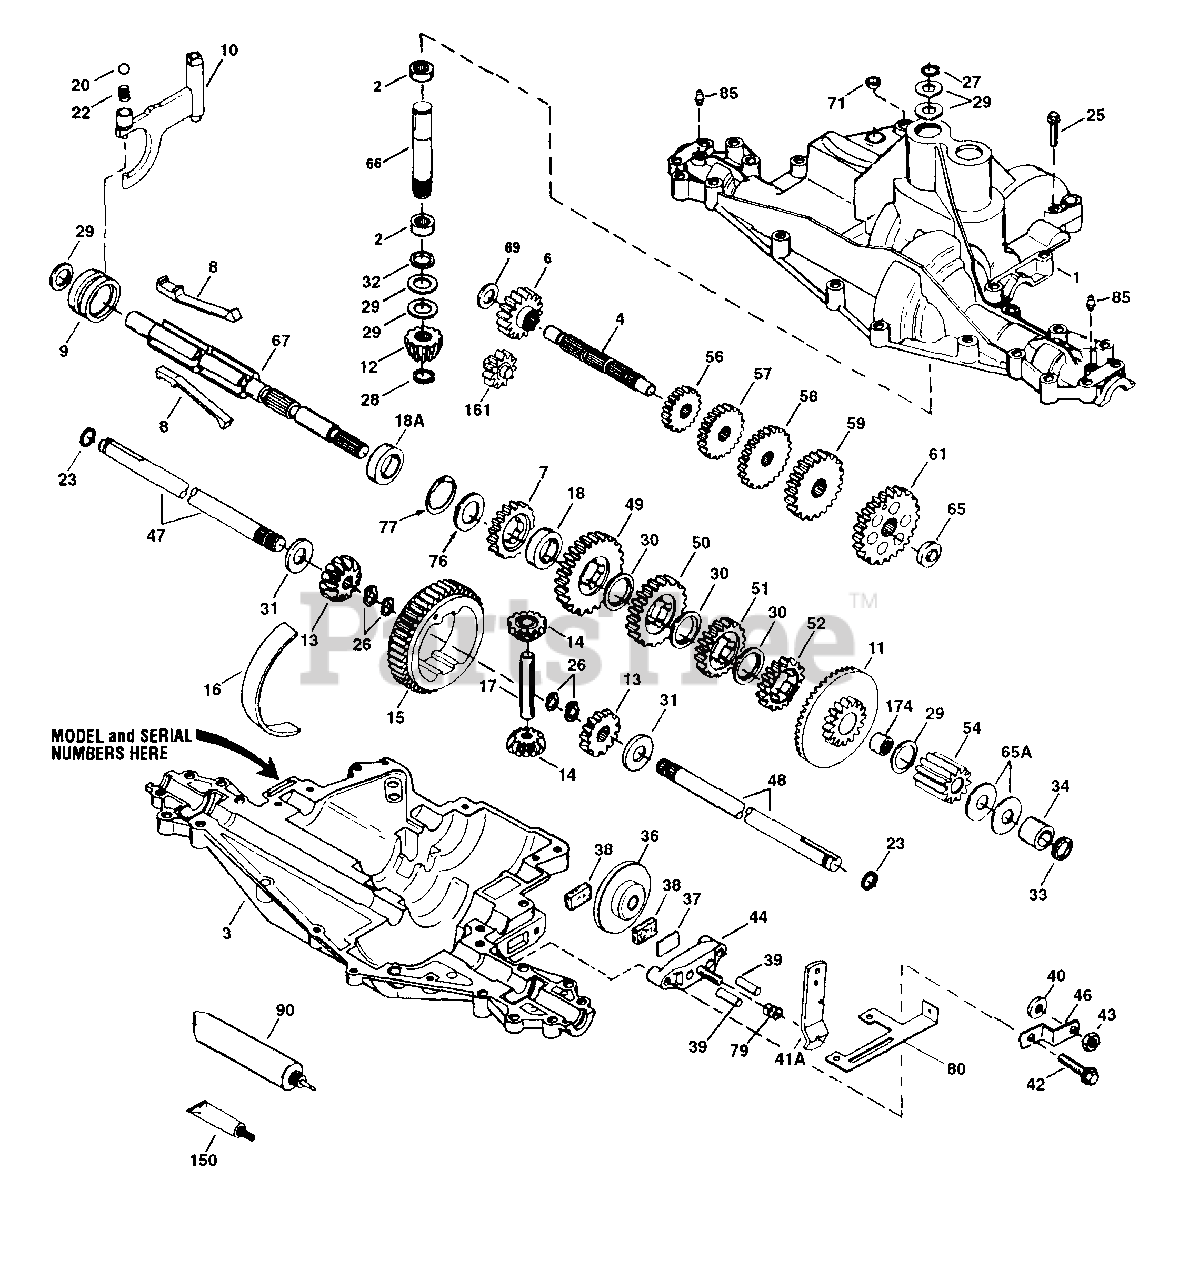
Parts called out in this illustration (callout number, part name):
1	Transaxle Cover
2	Needle Bearing
3	Transaxle Case
4	Countershaft
6	Spur Gear
7	Spur Gear
8	Shift Key
9	Shift Collar
10	Shift Rod & Fork
11	Bevel Gear & Bearing
12	Bevel Pinion
13	Bevel Gear
14	Differential Pinion
16	Bearing Strip
18	Neutral Spacer
18A	Neutral Spacer
20	Ball, 5/16" dia
25	Screw, 1/4-20 x 1-1/4"
26	Retaining Ring
27	Retaining Ring
28	Retaining Ring
36	Brake Disk
37	Brake Pad Plate
38	Brake Pad
40	Washer
41	Brake Lever
42	Screw, 1/4-20 x 1-1/4"
43	Locknut, 5/16-24
44	Brake Pad Holder
46	Brake Lever Bracket
47	Axle
48	Axle
49	Spur Gear
50	Spur Gear
51	Spur Gear
52	Spur Gear
54	Spur Gear
56	Spur Gear
57	Spur Gear
58	Spur Gear
59	Spur Gear
61	Spur Gear
66	Input Shaft
67	Shifter & Brake Shaft
71	Square Cut Ring
77	Inverted Retaining Ring
80	Brake Bracket
85	Lubrication Fitting
90	Grease
150	Gasket Eliminator
161	Reverse Idler
174	Needle Bearing
